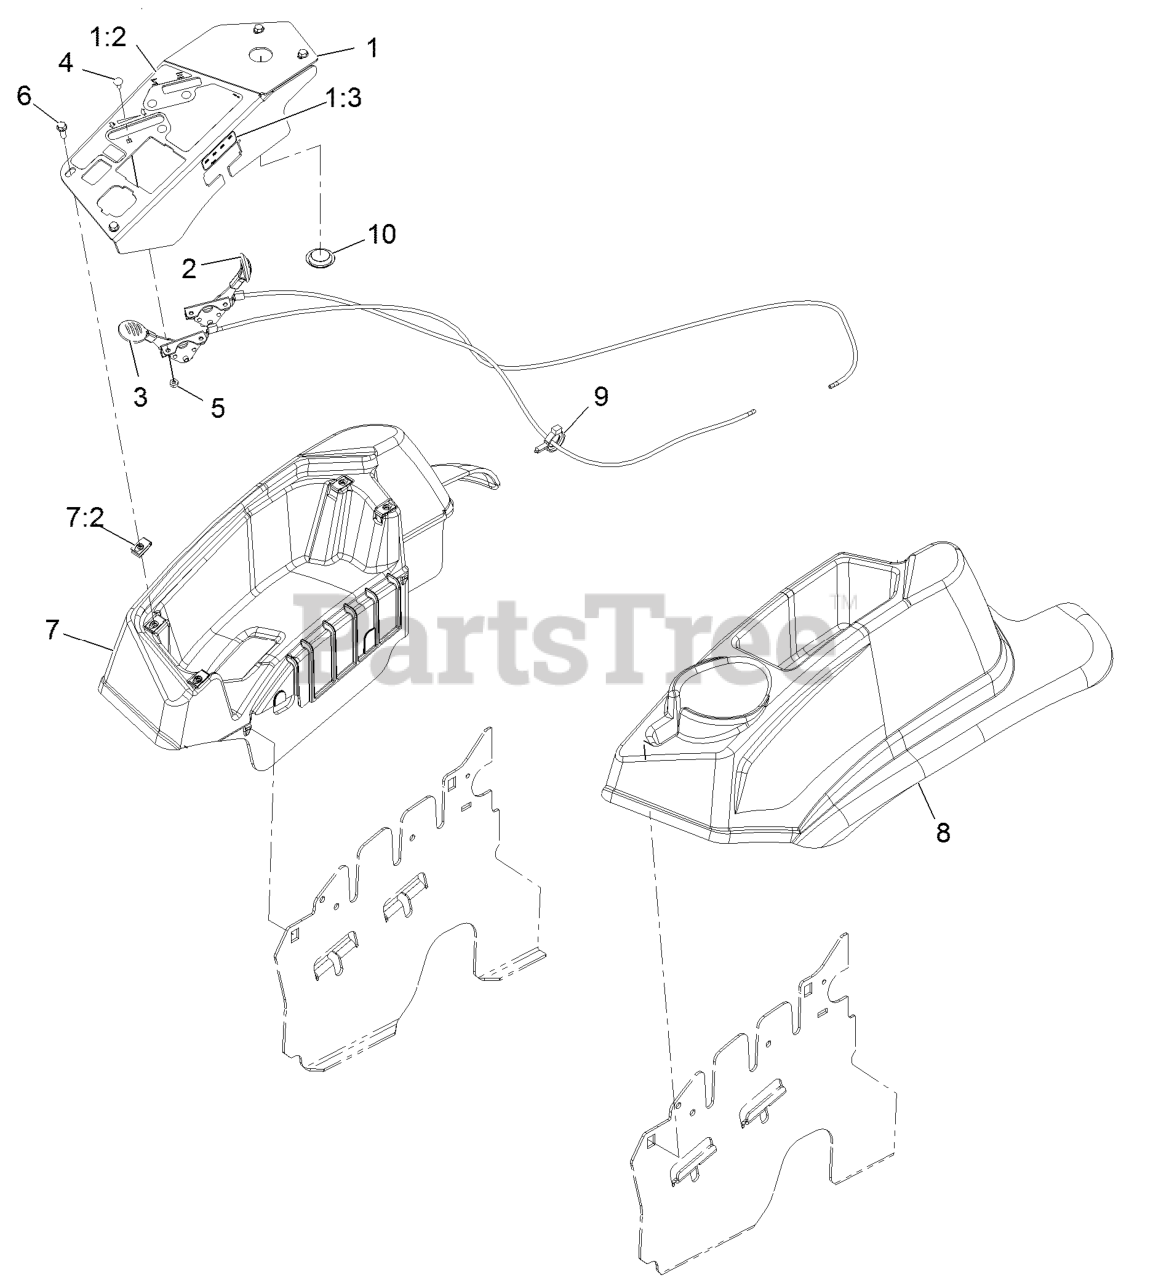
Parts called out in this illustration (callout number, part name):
1	CONSOLE,PANEL W/DECAL
1:2	DECAL-CONTROL PANEL
1:3	DECAL-FUSE
2	ASM, CHOKE CABLE
3	ASM,THROTTLE CABLE
4	BOLT-CARR
5	NUT-LOCK, NI
6	SCREW-HWH
7	CONSOLE,RH AS ASM
7:2	Nut-Retainer-Panel 1/4-20
8	CONSOLE, LH AS
9	CLAMP-HOSE
10	PLUG-PLASTIC
